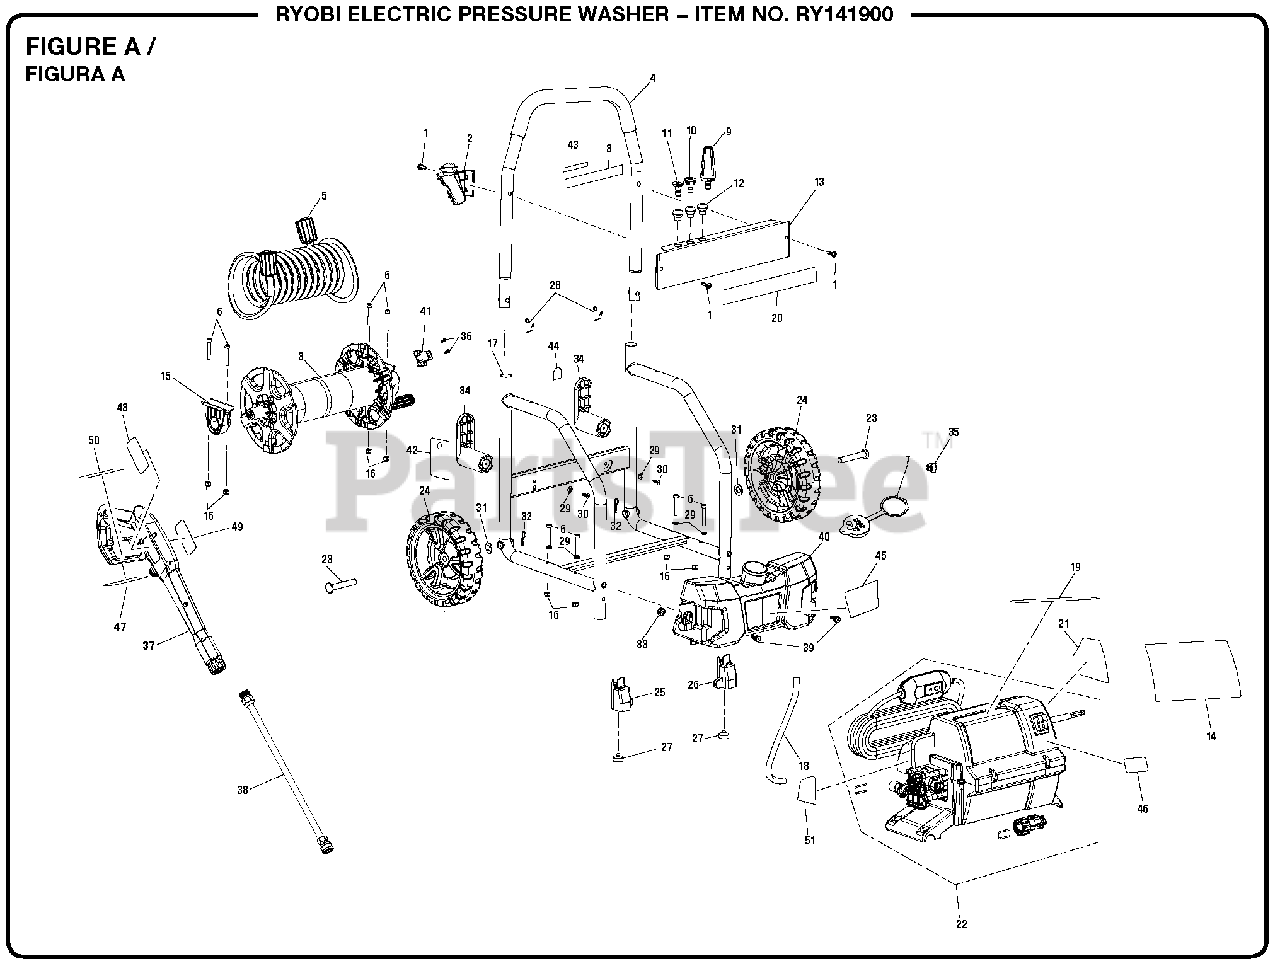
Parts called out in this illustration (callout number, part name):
1	Bolt (M6 x 20 mm)
2	Trigger Handle Holder
3	Hose Reel Assembly
4	Handle Assembly
5	High Pressure Hose
6	Screw (M6 x 40 mm)
7	Detergent Tank Cap
8	Quick Start Label
9	Turbo Nozzle
10	Soap Nozzle
11	15° Nozzle
12	Nozzle Grommet
13	Performance Panel
14	Logo Label
15	Hose Reel Bracket
16	Lock Nut (M6)
17	Main Frame
18	Injection Hose
19	Nozzle Select Label
20	Performance Label
21	Danger Label
22	Pump Housing Assembly
23	Wheel Axle
25	Foot (Left)
26	Foot (Right)
28	Spring Clip w/Button
29	Washer (M6)
30	Screw (M4.8 x 19 mm, Phillips Hd. S.T.)
31	Washer (ID125 x OD24 x 2t)
32	Hitch Pin
33	Soap Tank Grommet
34	Cord Wrap Arm
35	Cord Clamp
36	Screw (M4.2 x 15 mm, Phillips Hd. S.T.)
37	Trigger Handle
38	Spray Wand
39	Shoulder Bolt (M6 x 16 mm)
40	Detergent Tank
41	Hose Clip
42	Warning Hangtag
43	Inquires Label
44	Cord Unlock Label
45	Detergent Tank Label
46	On/Off Switch Label
47	Trigger Handle Rating Label
48	Trigger Handle Logo Label
49	Trigger Handle Warning Label (English)
50	Trigger Handle Warning Label (French/Spanish)
51	Pump Label
